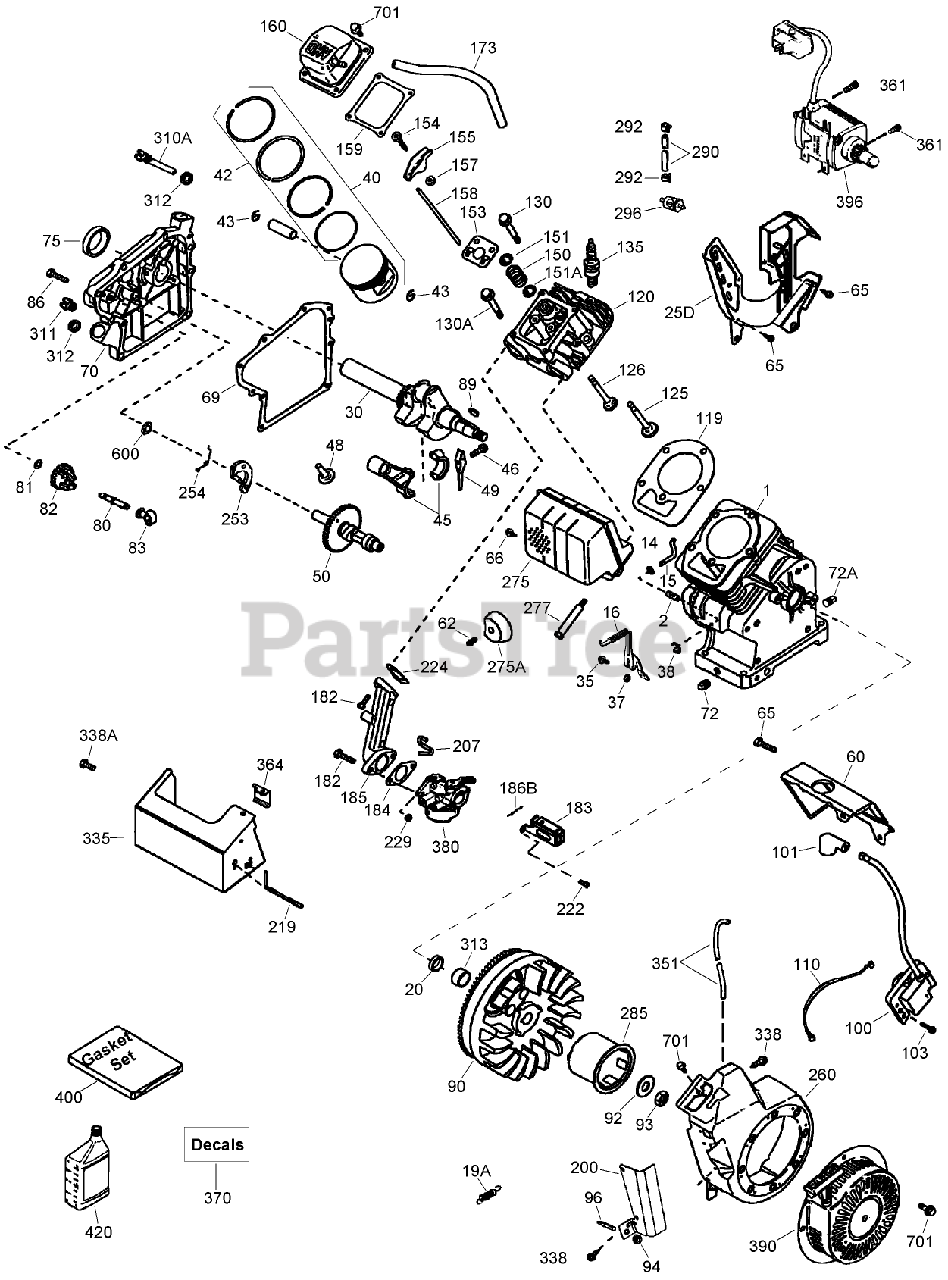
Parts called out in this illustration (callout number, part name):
135	Spark Plug-Resistor (R N 4C)
150	Spring-Valve
151	Cap-Valve, Spring
151A	Seal-Valve, Intake
153	Guide-Rod, Push
154	Stud-Arm, Rocker
155	Arm-Rocker
157	Nut (1/4-28)
158	Rod-Push
159	Gasket-Cover, Rocker Arm
160	Cover-Arm, Rocker
173	Breather Tube
182	Screw (1/4-20 x 1)
183	Bracket-Choke
184	Gasket
185	Pipe-Intake
186B	Spring-Choke
200	Bracket-Control
207	Link-Throttle
219	Rod-Choke
222	Screw (10-32 X 15/32)
224	Gasket-Pipe, Intake
229	Nut (1/4-20)
253	Weight-Release, Compression
254	Spring-Release, Compression
260	Housing-Blower
275	Muffler (Carburetor Side Discharge)
275A	Deflector-Muffler
277	Screw (1/4-20 x 2-9/32)
285	Cup-Starter
290	Line-Fuel, Low Permeation (16.0)
292	Clamp-Line, Fuel
296	Filter-Fuel (also available in Packaged Part 740093) (Includes 292)
310A	Dipstick (Includes 312)
311	Plug-Fill, Oil (Includes 312)
312	Gasket
313	Spacer
335	Cover-Carburetor
338	Screw (10-32 x 1/2)
338A	Screw (10-32 x 3/8)
351	Line-Primer
361	Screw (T-30, 1/4-20x15/32)
364	Bracket-Cover, Carburetor
370	Decal-Tecumseh Logo for Top of Recoil Starter
380	Carburetor (Includes 184)
390	Starter-Rewind
396	Electric Starter Motor Asm (220 Volt)
400	Gasket Set
420	Oil-Engine, S A E 5W30
600	Washer
701	Screw (1/4-20 x 31/64)
999	Winter Maintenance Kit (S A E 5W30 Oil)
